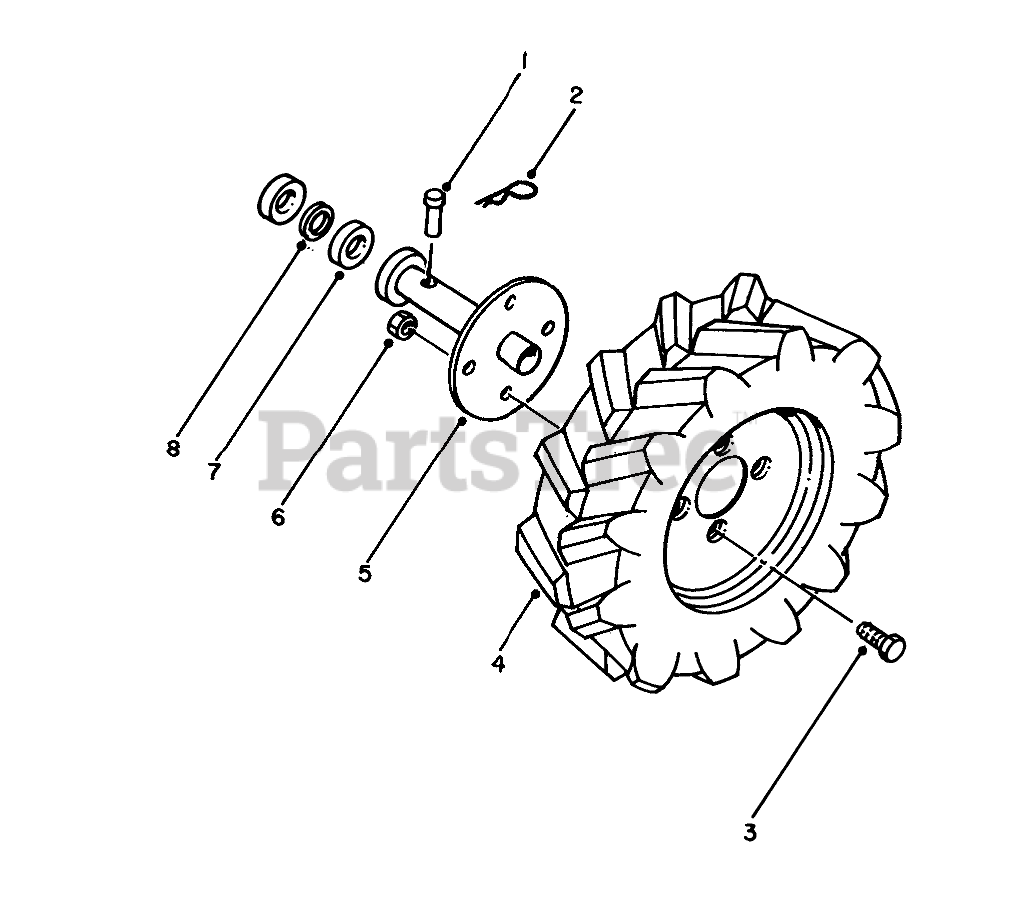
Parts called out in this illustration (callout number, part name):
1	Clevis Pin
2	Spring Clip
3	Lug Bolt
4	Tire and Wheel Assembly L.H.
5	Adapter
6	NUT-HEX
7	Felt Seal
8	Washer
